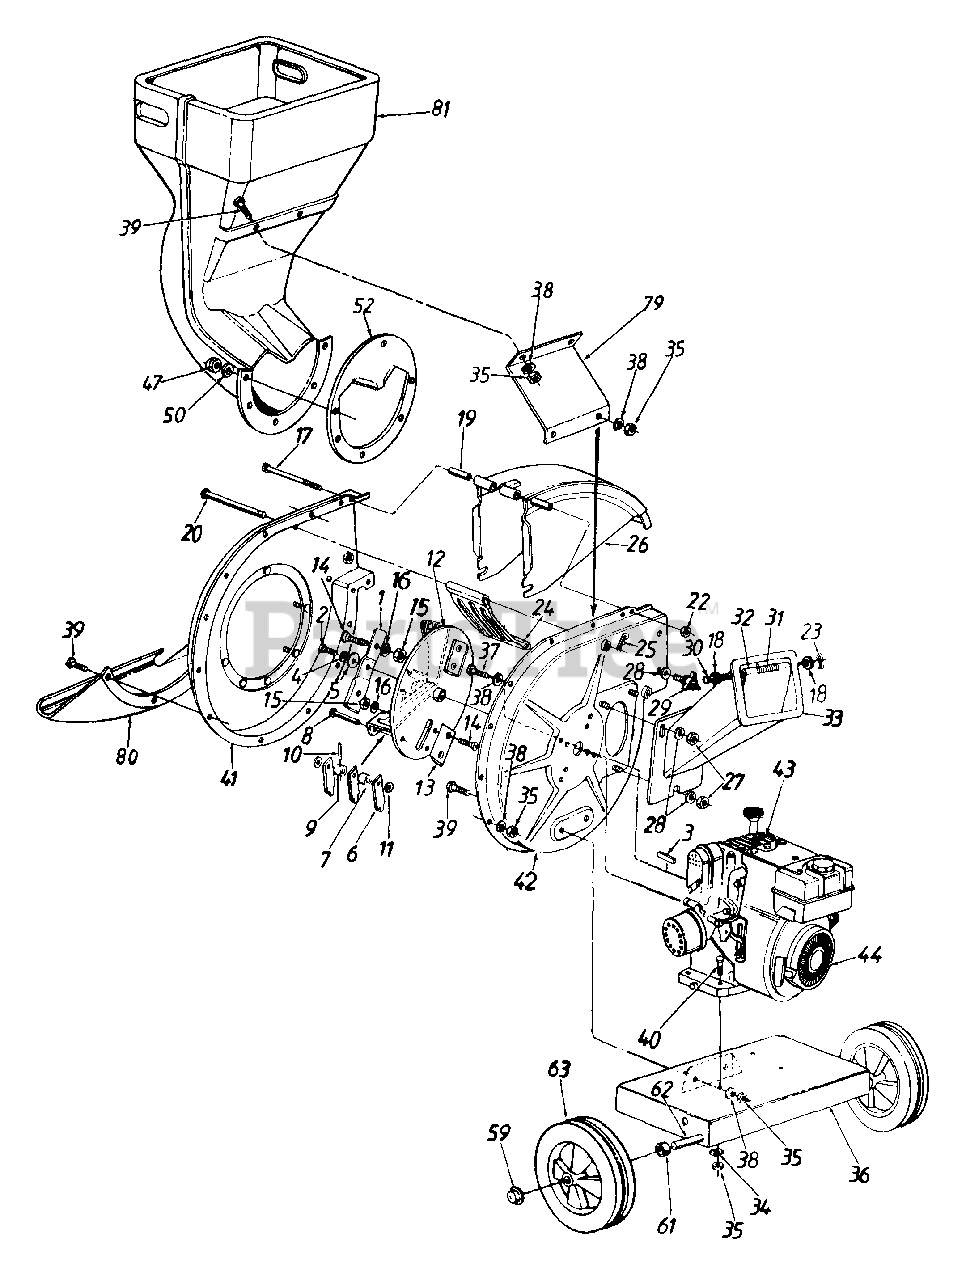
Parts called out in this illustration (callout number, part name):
1	Blade
3	Sq. Key 1/4 x 2.0" Lg.
4	L-Wash. 3/8" I.D. H.D.
5	Fl-Wash. .406" I.D. x 1.25" O.D. Hdn.
6	Flail
7	Flail Spacer
8	Clevis Pin .496" Dia.
9	Flail Spacer w/.160" Dia. Hole
10	Spring Roll Pin 1.12" Lg.
11	Fl-Wash. .531" I.D. x .94" O.D.
12	Impeller Ass'y. Comp.
13	Chipper Blade
14	Flat Hd. Scr. 5/16-24 x .75" Lg.
15	Hex Top L-Nut 5/16-24 (Gr, 5)
16	L-Wash. 5/16" I.Q.
17	Hex Bolt 1/4-20 x 3.75" Lg.
18	Fl-Wash. .281" I.D. x .50" O.D.
19	Chute Hinge Spacer 1.66" Lg.
20	Clevis Pin .5" Dia. x 4.62" Lg.
22	Hex Ctr. L-Nut 1/4-20 Thd.
23	Cotter Pin
25	Internal Cotter Pin 3/8" Dia.
27	Hex Nut 5/16-18 Thd. (Gr. 5)
28	Bell-Wash. .345" I.D. x .88"
29	Hand Knob
30	Chipper Door Rod
31	Torsion Spring 1.14" Lg.
35	Hex Nut 5/16-18 Thd. (Gr. 5)
36	Shredder Frame
37	Hex Bolt 5/16-24 x .75" Lg.
38	L-Wash. 5/16" I.D.
39	Hex Bolt 5/16-18 x .75" Lg. (Gr. 5)
40	Hex Bolt 5/16-18 x 1.75" Lg.
44	Engine
47	Elastic Lock Nut 5/16-18 Thd.
50	Fl-Wash. 5/16" I.D.
52	Back-Up Plate
59	Push Cap 5/8" Dia. Rod
61	Spacer .64" I.D. x .38" Lg.
62	Shredder Axle
63	Wheel Ass'y. Comp.
81	Leaf Hopper
